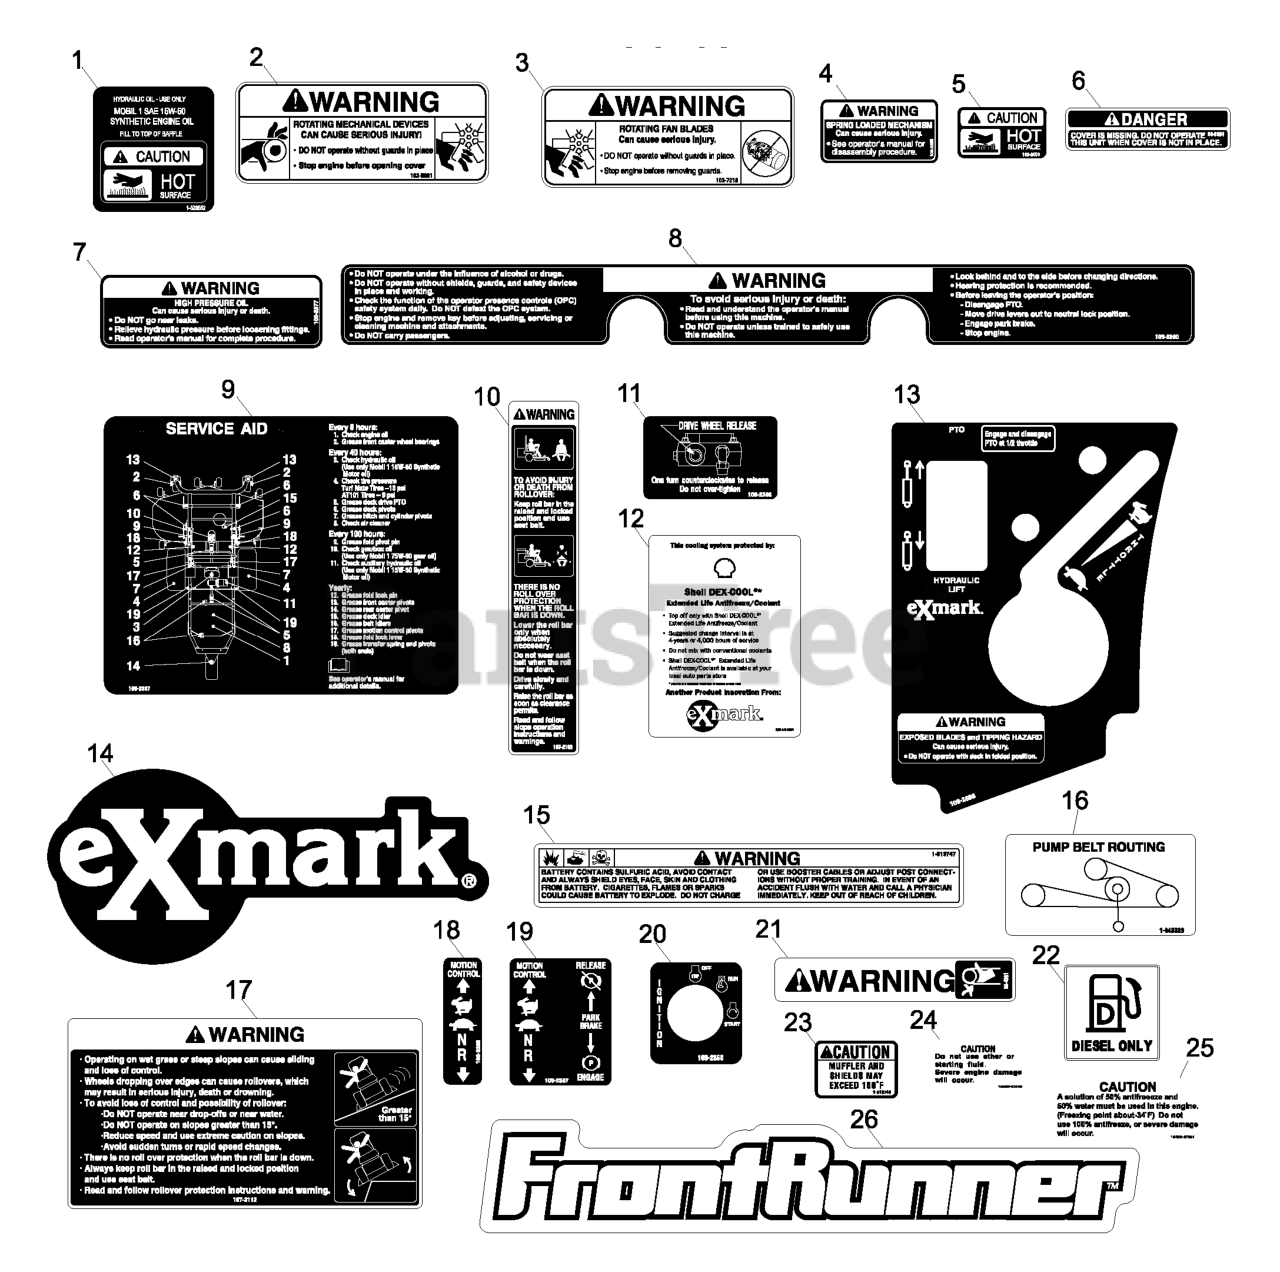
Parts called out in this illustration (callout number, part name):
2	DECAL-DEVICES, ROTATING
3	DECAL,PUMP FAN WARNING
4	DECAL,SPRING LOADED
5	DECAL-CAUTION
6	DECAL-COVER, MISSING
7	DECAL,HIGH PRESSURE OIL
8	DECAL,TOP CONSOLE
9	Decal, Service Aid
10	DECAL-WARNING, FOLDING RO
11	DECAL,PUMP DRIVE RELEASE
12	DECAL,SHELL COOLANT
13	DECAL,CONSOLE FMZ DIESEL
14	DECAL,EXMARK LOGO
15	DECAL-BATTERY
16	DECAL-ROUTING, BELT
17	DECAL-WARNING
18	DECAL-CONTROL, MOTION
19	DECAL,MOTION CNTL/PARK BR
20	DECAL,IGNITION
21	DECAL-WARNING
22	DECAL-FUEL
24	DECAL-CAUTION
25	DECAL-ANTIFREEZE
26	DECAL,FRONTRUNNER
